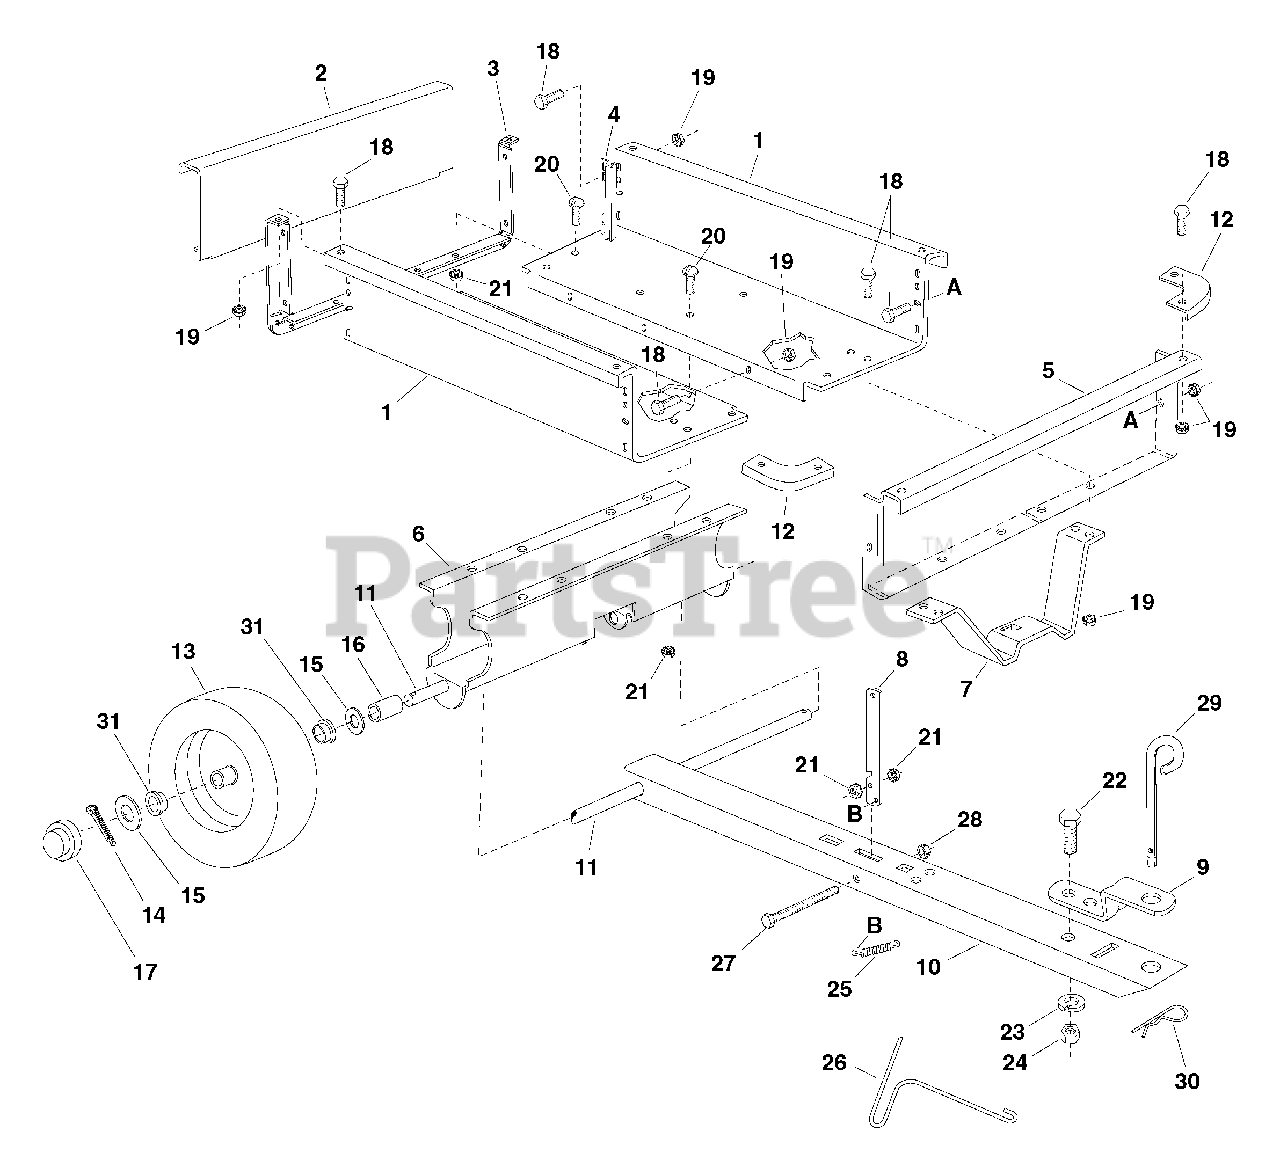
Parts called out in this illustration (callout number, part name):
1	Cart Body
2	Tailgate
3	Tailgate Reinforcement Bracket
4	Guide, Tailgate
5	Front Panel
6	Wheel Support
7	Latch Stand Bracket
8	Latch Lock Lever
9	Hitch Bracket
10	Draw Bar Tongue
11	Axle, Wheel 3/4" Dia.
12	Cap, Front Corner
13	Wheel, 16/4.00 x 8.00
14	Cotter Pin, 1/8" Dia. x 1"
15	Washer, Flat 3/4"
16	Spacer Tube, 1-1/4" O.D. x 2" Lg.
17	Hub Cap
18	Hex Bolt, 1/4-20 x 1/2"
19	Hex Nut, 1/4-20 (SEMS)
20	Truss Hd. Bolt, 5/16-18 x 3/4" Lg.
21	Hex Nut, 5/16-18 (SEMS)
22	Hex Bolt, 3/8-16 x 1" Lg.
23	Lock Washer, 3/8"
24	Hex nut, 3/8-16
25	Extension Spring
26	Spring Puller Tool
27	Hex Bolt, 5/16-18 x 3-3/4
28	Hex Lock Nut, 5/16-18
29	Hitch Pin
30	Hair Cotter Pin, 1/8" (#4)
31	Wheel Bearing
